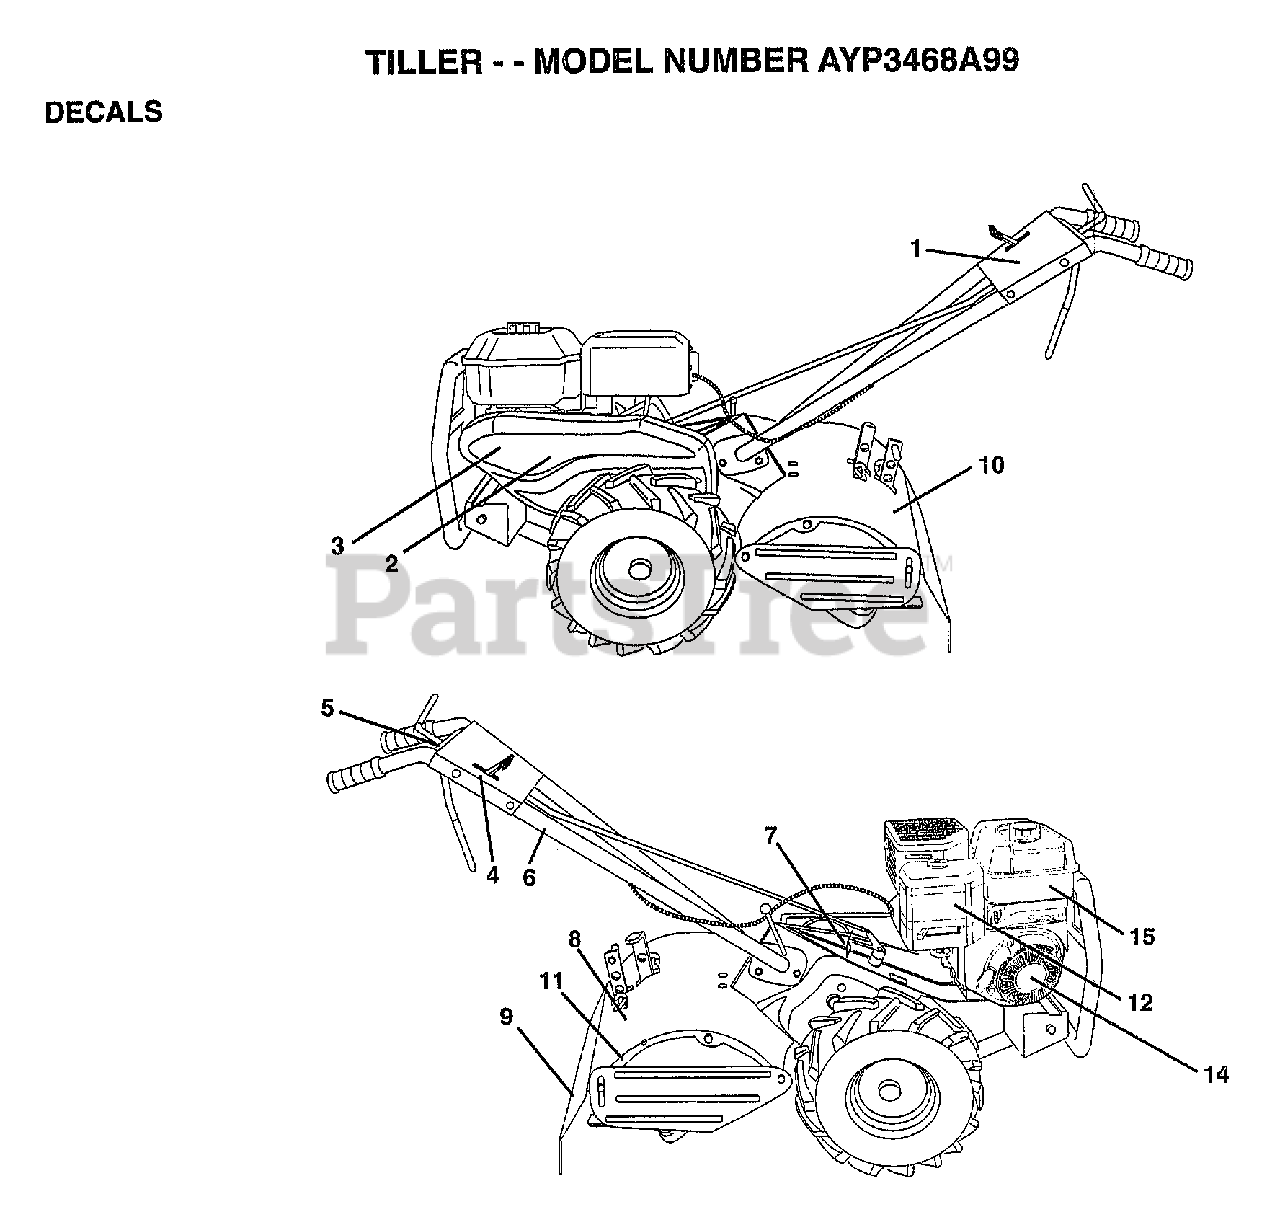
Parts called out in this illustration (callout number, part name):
4	DECAL REVERSE
6	DECAL TI
7	DECAL
9	DECAL TI
10	DECAL.DRAG.STAKE.LH.TIL
11	DECAL.TINE.SHIELD
12	DECAL, CHOKE
13	DECAL.DEPTH.STAKE.RH.TIL
14	"DECAL,ENGINEOHP REF"
